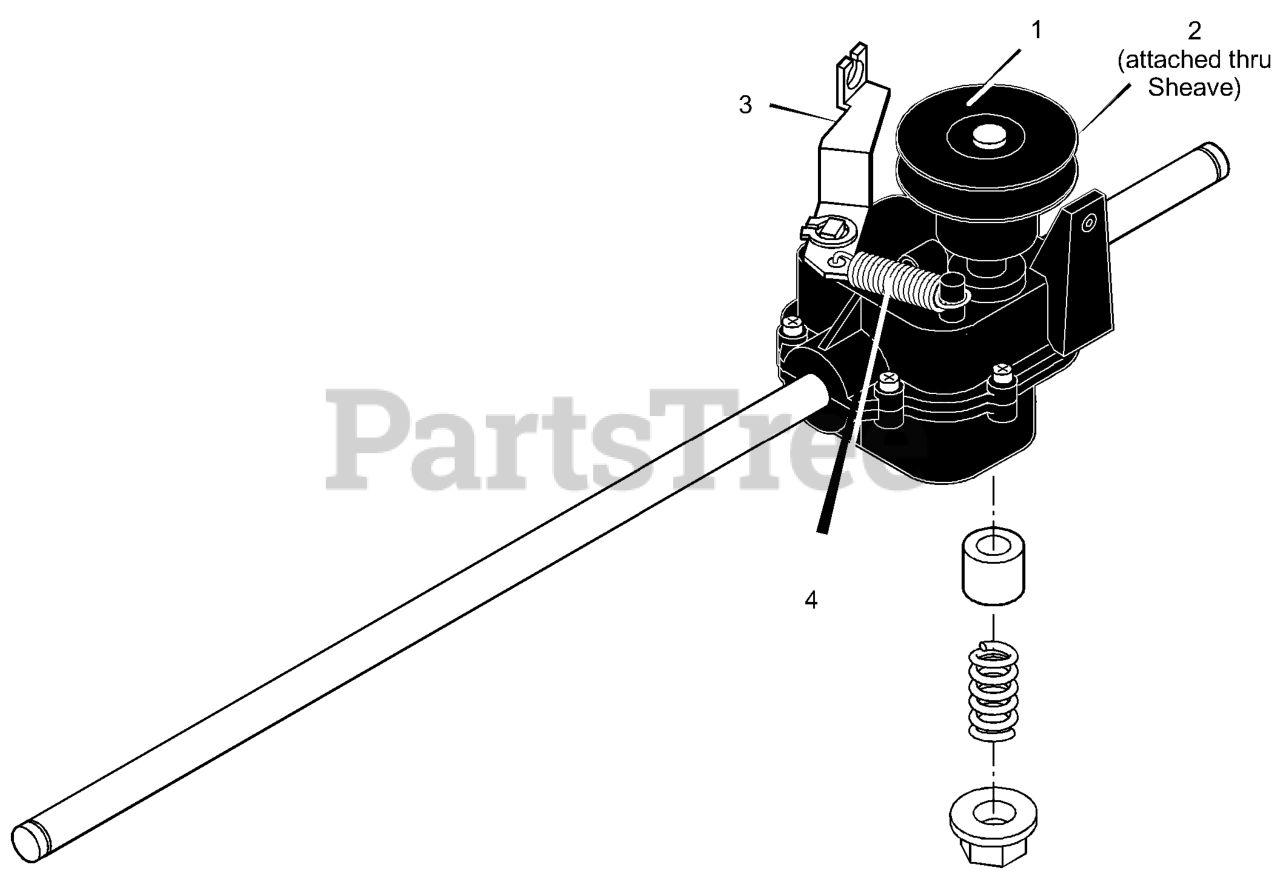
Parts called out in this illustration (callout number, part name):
2	Attachment Pin, Pulley
3	Clutch Lever Assembly
4	Spring, Clutch Return
